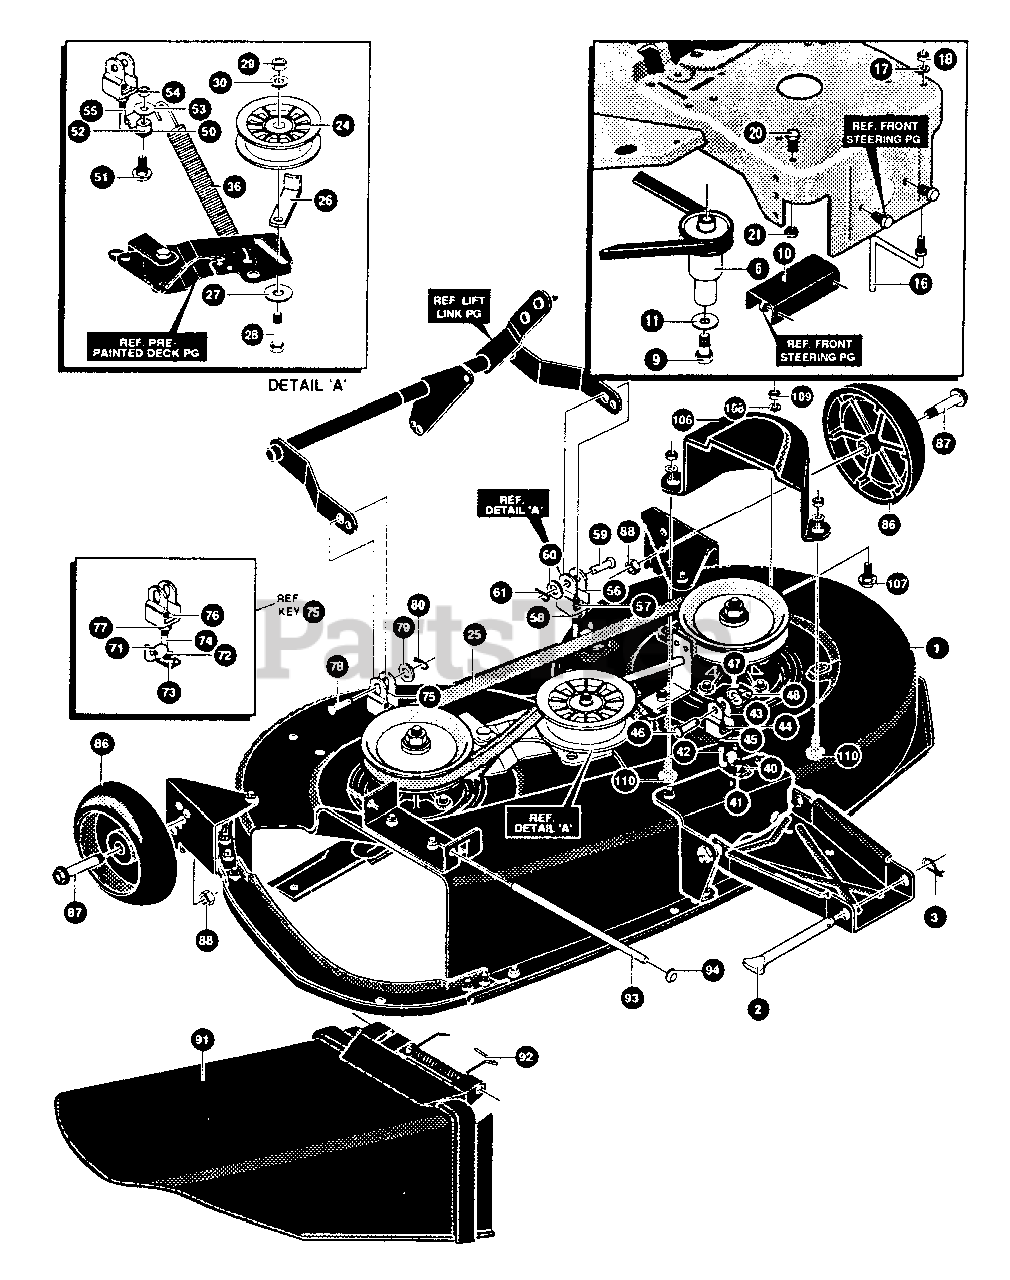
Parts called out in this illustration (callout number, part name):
1	40 DECK EC,LL,ZERKS,W/O-ROLL
2	ROD, DRAWBAR
3	PIN, HAIR .091 DIAX1.62LG
6	PULLEY, ENGINE EL/CL EURO LT
10	BRACKET, CLUTCH STOP 40/46 E/C
16	BELT GUIDE
17	WASHER, REGINTLK .320X.61X.03
18	NUT, 5/16-18 REGHEXCTRLK
20	SCREW, 5/16-18X.75
21	NUT, 5/16-18 REGHEXCTRLK
24	PULLEY, IDLER BFF 4.00 WIDE
25	BELT, V 5L 83.0 40" DECK
26	RETAINER, BELT
27	WASHER, FLAT .375X .88X .082
28	BOLT, 3/8-16X2.00 CARR
29	NUT, 3/8-16 REGHEX
30	WASHER, REGSPTLK .393X.68X.10
36	SPRING, 40&43" (12 TO 20 HP EC)
40	CLIP, 40/46 HANGER
41	NUT, 5/16-18 REGHEXCTRLK
42	ROD, 40" REAR DECK LIFT
44	NUT, 1/2-13 .458 SQ
45	NUT, 1/2-13 HEXJAM
46	PIN, CLEVIS .375DIA X .81 LG
47	WASHER, FLAT .406X.81X.065
48	PIN, HAIR .091 DIAX1.62LG
50	CLIP, 40/46 HANGER
51	CARR BOLT, 5/16-18X1.00
53	FLATWASHER, .328X1.06X.062
54	NUT, 5/16-18 REGHEXCTRLK
55	ROD, 40" REAR DECK LIFT
57	NUT, 1/2-13 .458 SQ
58	NUT, 1/2-13 HEXJAM
59	PIN, CLEVIS .375DIA X .81 LG
60	FLATWASHER, .406X.81X.065
61	PIN, HAIR .091 DIAX1.62LG
71	CLIP, 40/46 HANGER
72	SCREW, 5/16-18X.75 HHC
73	NUT, 5/16-18 REGHEXCTRLK
74	ROD, 40" REAR DECK LIFT
75	CLEVIS SLOT EURO
76	NUT, 1/2-13 .458 SQ
77	AUT, 1/2-13 HEXJAM
78	PIN, CLEVIS .375DIA X .81 LG
79	WASHER FLAT .406X.81X065
80	PIN, HAIR .091 DIAX1.62LG
86	GAUGE WHEEL,EUR06000DX1.38WD
87	BOLT, .500X1.390 HHSH 3/8-16
88	NUT, 3/8-16 REGHXCTRLK
91	CHUTE DEFLECTOR 40",42"&43"
92	SPRING TORSION CHUTE DEFLECTOR
93	ROD,PIVOT DECK .312DX7.25
94	NUT, PUSH ON CAP .312 OD
106	GUARD, BELT LH PLASTIC
107	SCREW, 5/16-18X.75 HHC
108	WASHER, FLAT .344X.69X.065
109	NUT, 5/16-18 REGHEXCTRLK
110	BOLT, 5/16-18X.63 CARR
